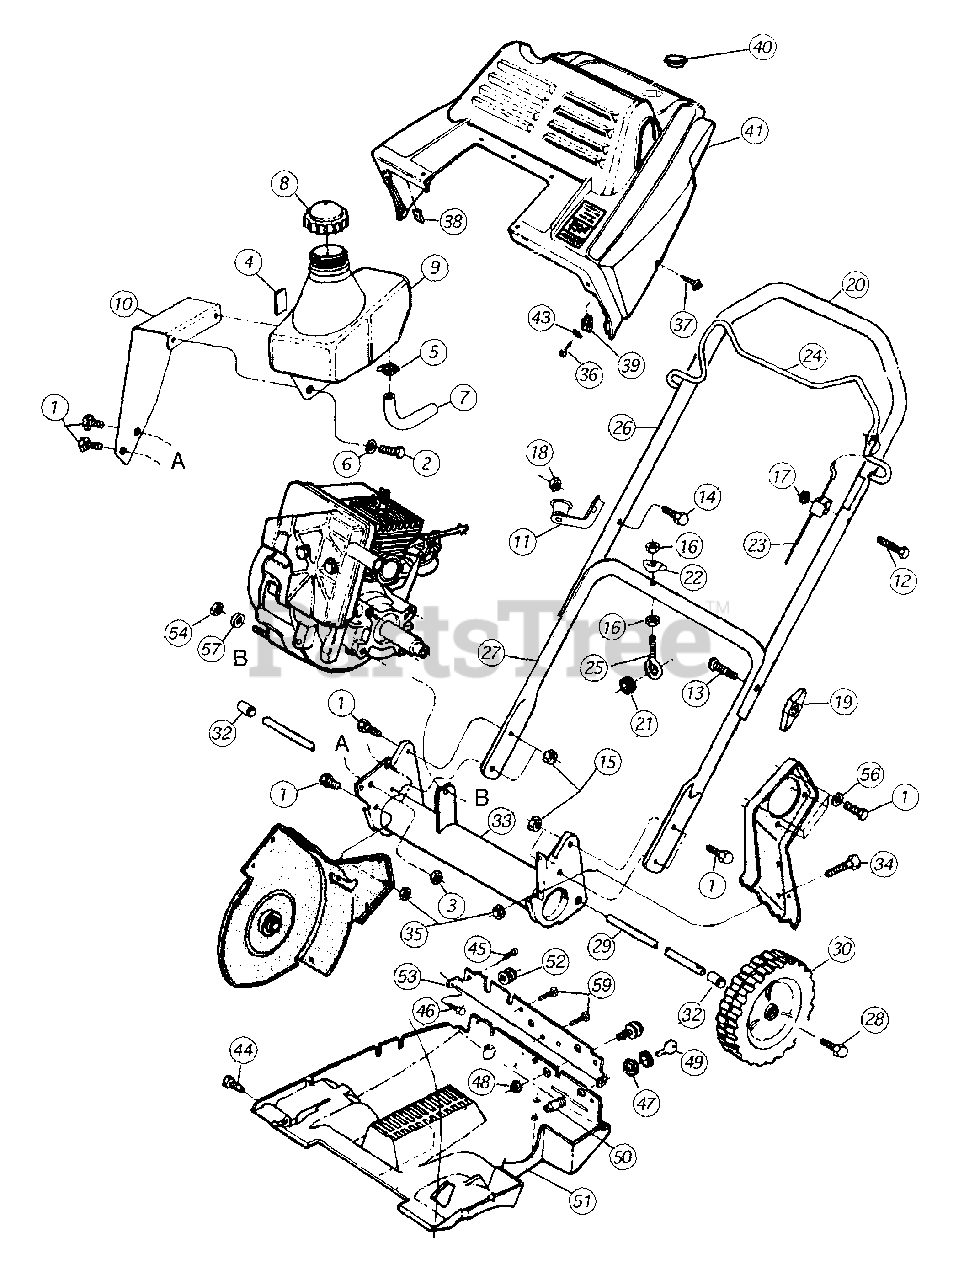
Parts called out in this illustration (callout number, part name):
1	Hex Screw: 5/16 - 18 x .75 Gr 2
2	Hex Screw: 1/4 - 14 x .625
3	Nylock Nut
4	Foam Strip
5	Hose Clamp 1/2" OD
6	Flat Washer
7	Hose, Fuel Line
8	Fuel Tank Cap
9	Fuel Tank
10	Support Bracket
11	Bracket Assembly, Rope Guide
12	Hex Screw: 1/4 - 20 x 2.0 Gr 5
13	Carriage Bolt: 5/16 - 18 x 2.0 Lg. Carved
14	Oval C-Sunk Screw
15	Nylock Nut
16	Hex Nut: 5/16 - 18
17	Top Lock Nut Nylon Insert
18	Top Lock Nut 1/4 - 20
19	Knob Assembly
20	Foam Grip, Handle
21	Grommet: .44 ID x .94 OD x .50
22	Side Lock Washer
23	Drive Cable, Auger
24	Auger Bail, Drive Dipped
25	Eye Bolt 5/16 - 18
28	Tap Screw: 3/8 - 16 x .5
29	Axle, Tube
30	Wheel Assembly
32	Spacer
33	Frame Assembly
34	Hex Cap Screw: 5/16 - 18 x 1.00
35	Nylock Nut
36	Hex Screw
37	Ab Screw
38	Retainer Clip, U-Style
39	U Nut
40	Snap-In Plug
41	Upper Engine Cover
43	Flat Washer
44	Hex Screw: 1/4 - 20 x .625
45	Tap Screw: 10 - 24 x .75
46	Tap Screw: 10 - 25 x .75
47	Jam Nut: 5/8 - 32 x .12
48	Top Lock Nut Nylon Insert
49	Ignition Key
50	Recoil Starter Key
51	Lower Engine Cover
52	Grommet: .280 x .750 x .40
53	Control Panel
54	Nylock Nut
56	Lock Washer
57	Flat Washer
59	Cord Assembly
